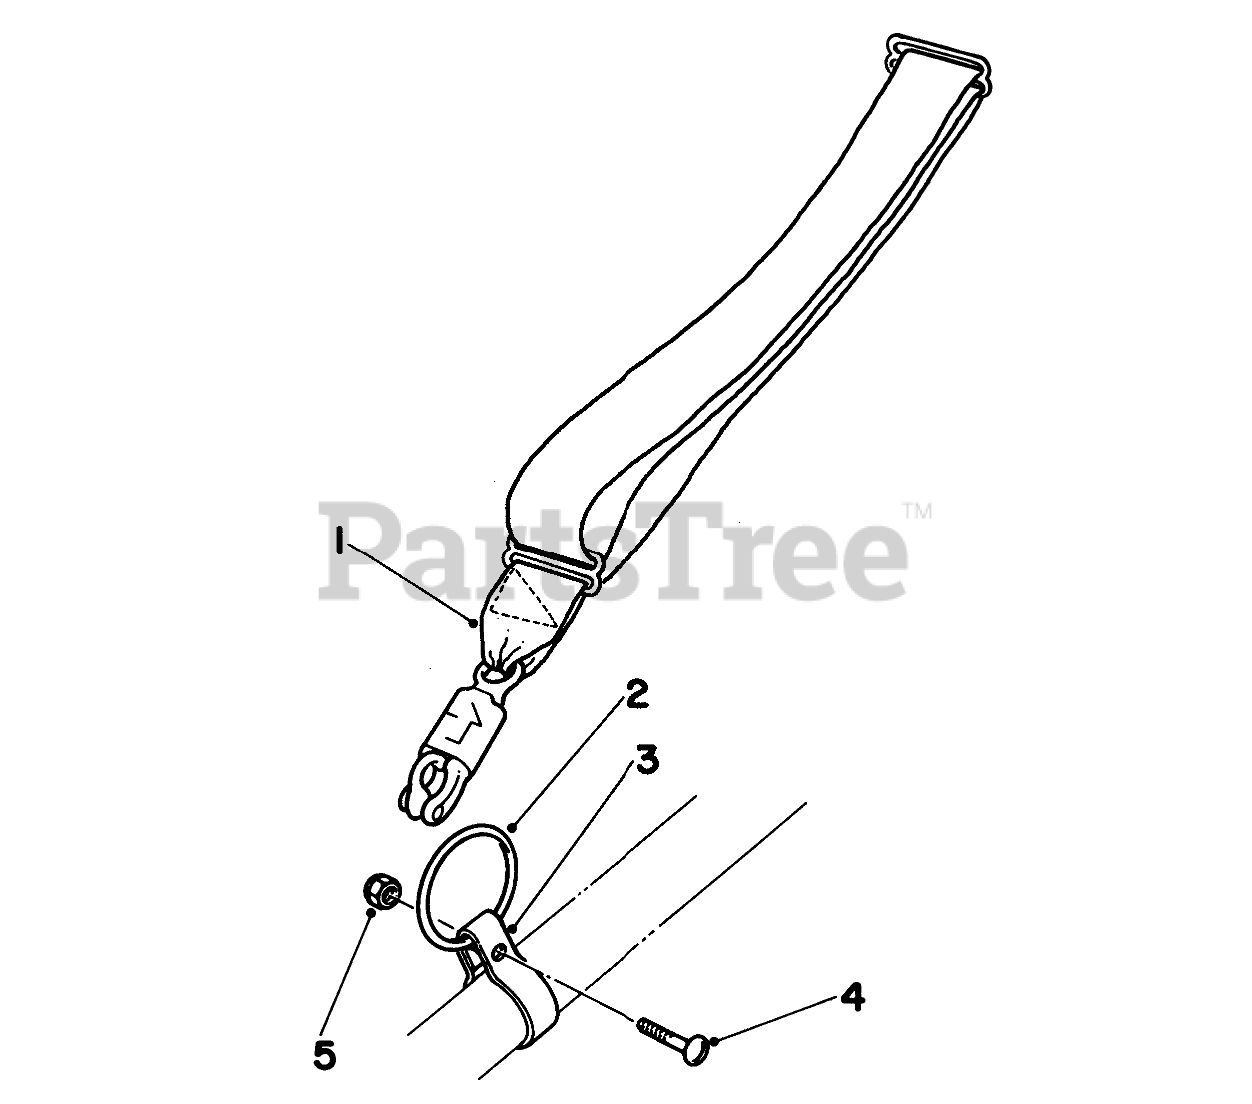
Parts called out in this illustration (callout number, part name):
1	Shoulder Strap
2	RING-HARNESS
3	HARNESS CLAMP
4	SCREW-SRH
5	NUT-LOCK, NI
